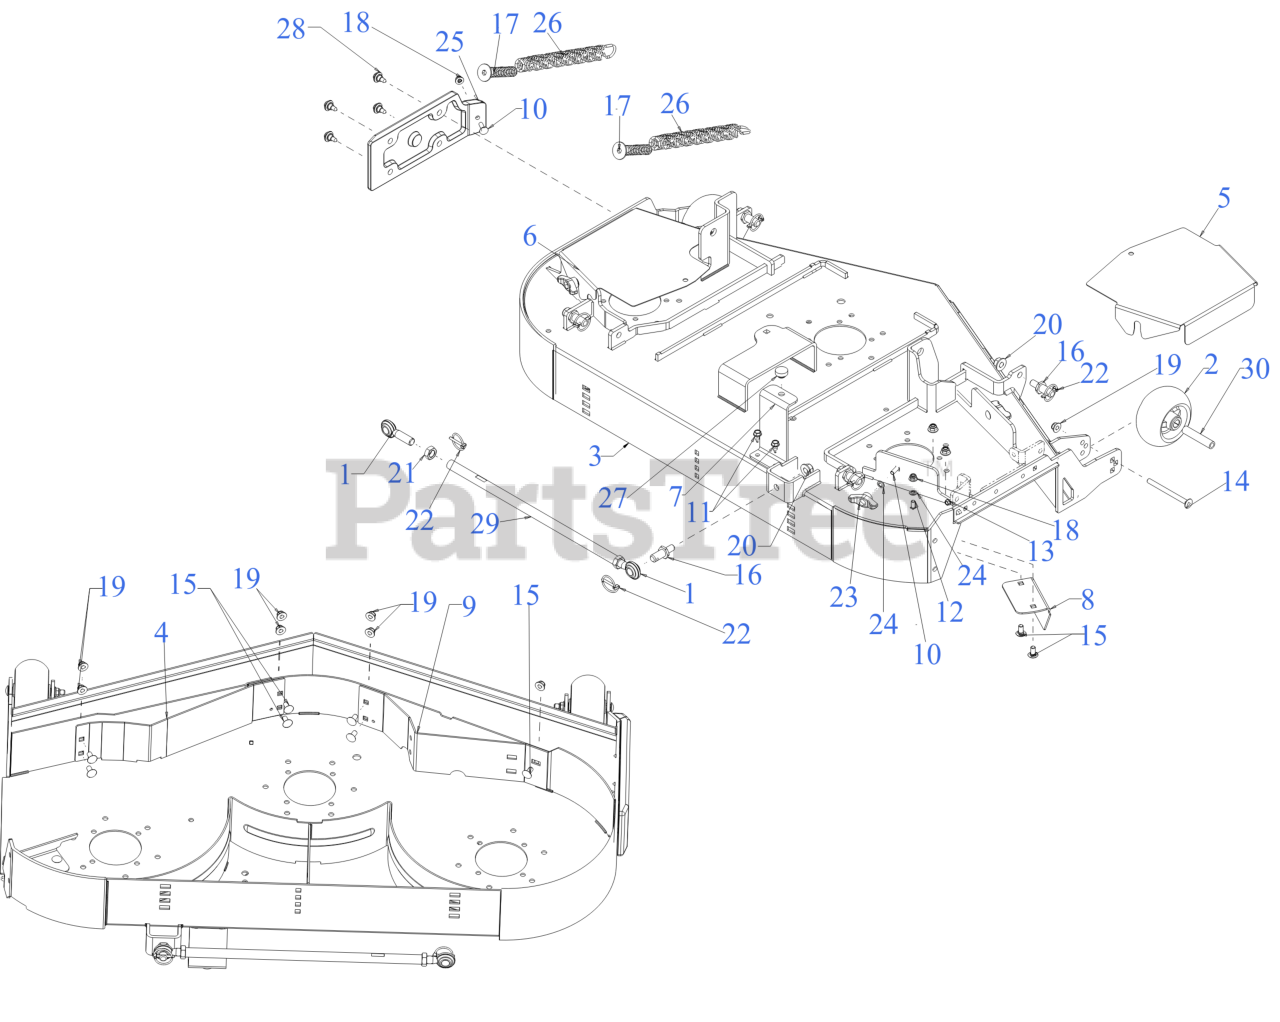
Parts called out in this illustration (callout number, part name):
1	MALE ROD END
2	5" DIA DECK WHEEL COMPLETE
2	FLANGE BEARING
3	48" FAB DECK
4	48" FAB DECK BAFFLE
5	BELT COVER (RH)
6	BELT COVER (LH)
7	DECK STOP BRACKET
8	DECK CHUTE BAFFLE
9	48" ADJUSTMENT BAFFLE
10	CARRIAGE BOLT 5/16-18 x 1.00
11	SCREW 5/16-18 x .750
12	CARRIAGE BOLT 5/16-18 x .75
13	SCREW 1/4-20 X.500
14	CARRIAGE BOLT 3/8-16 x 4.25 GR5
15	CARRIAGE BOLT 3/8-16 x .75
17	SPRING INSERT SCREW
18	FLANGE LOCK NUT 5/16-18
21	HEX JAM NUT 5/8-18
22	LYNCH PIN .1875
23	WING KNOB 5/16-18
25	DECK SKID PLATE (LH)
26	EXTENTION SPRING 1.20 x 11.35
27	RUBBER BUMPER 1.000 x .313
28	SHOULDER SCREW .43X.29X5/16-18 TT
29	TUBE .565 X .750 X 18.75"LG
30	WHEEL SPACER .38ID x 3.04LG
